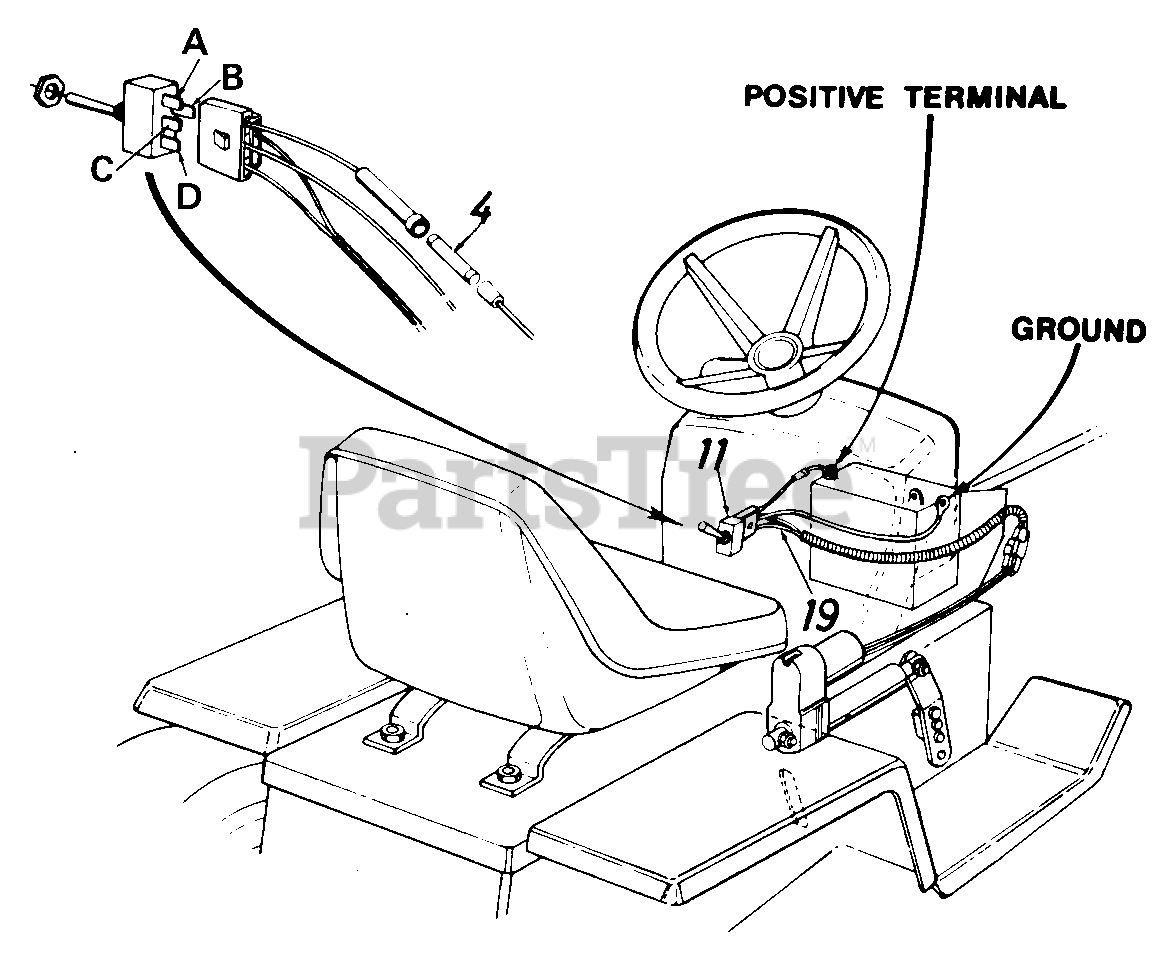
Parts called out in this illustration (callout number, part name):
4	Fuse 30 AMP
11	Toggle Switch
19	Wire Harness
A	Blue WireConnects to Positve Terminal on Battery
B	Yellow WireConnects to Actuator
C	Black WireGround Wire-to Frame
D	Red WireConnects to Actuator
